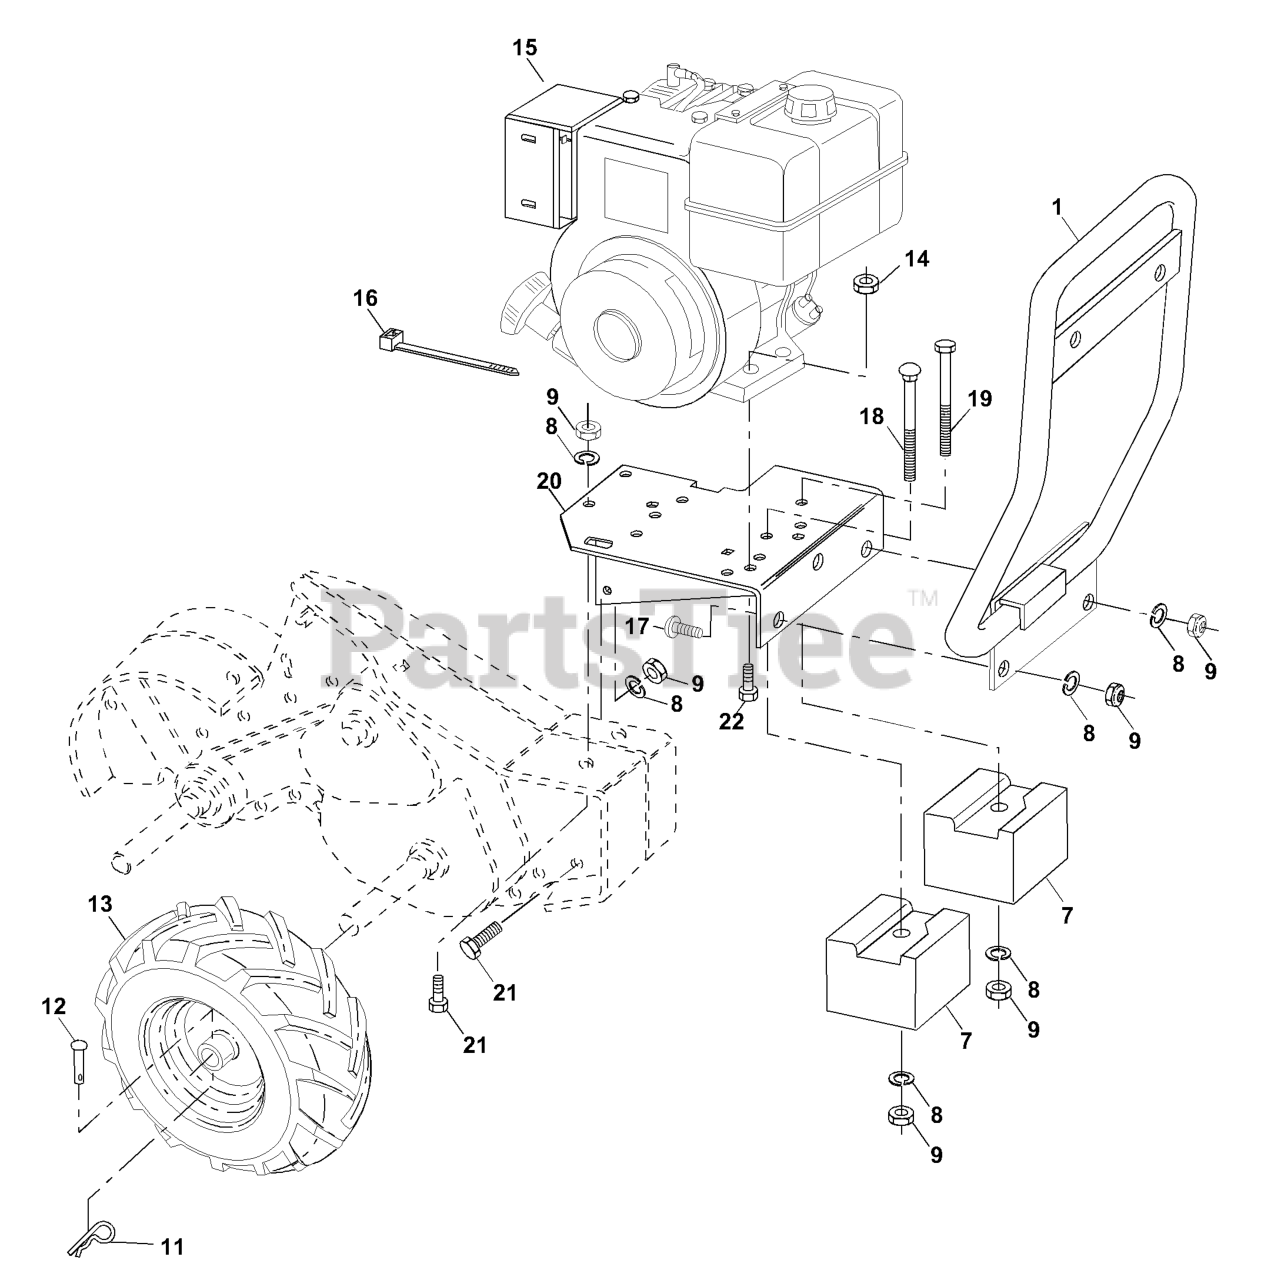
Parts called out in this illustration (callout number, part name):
7	COUNTER WEIGHT RH
8	WASHER, LOCK 3/8
9	NUT.HEX.3/8-16UNC
11	SPRING TI
13	TIRE.16X4-8.CHEVRON.TILLER
13	RIM
13	VALVE STEM LT
14	NUT
17	BOLT D
18	Bolt, Carriage 3/8-16 x 4-1/2
19	BOLT, HEX 3/8-16X4-1/2
20	ENGINE BRACKET
21	BOLT
22	BOLT, HEX 5/16-18X1-3/4
